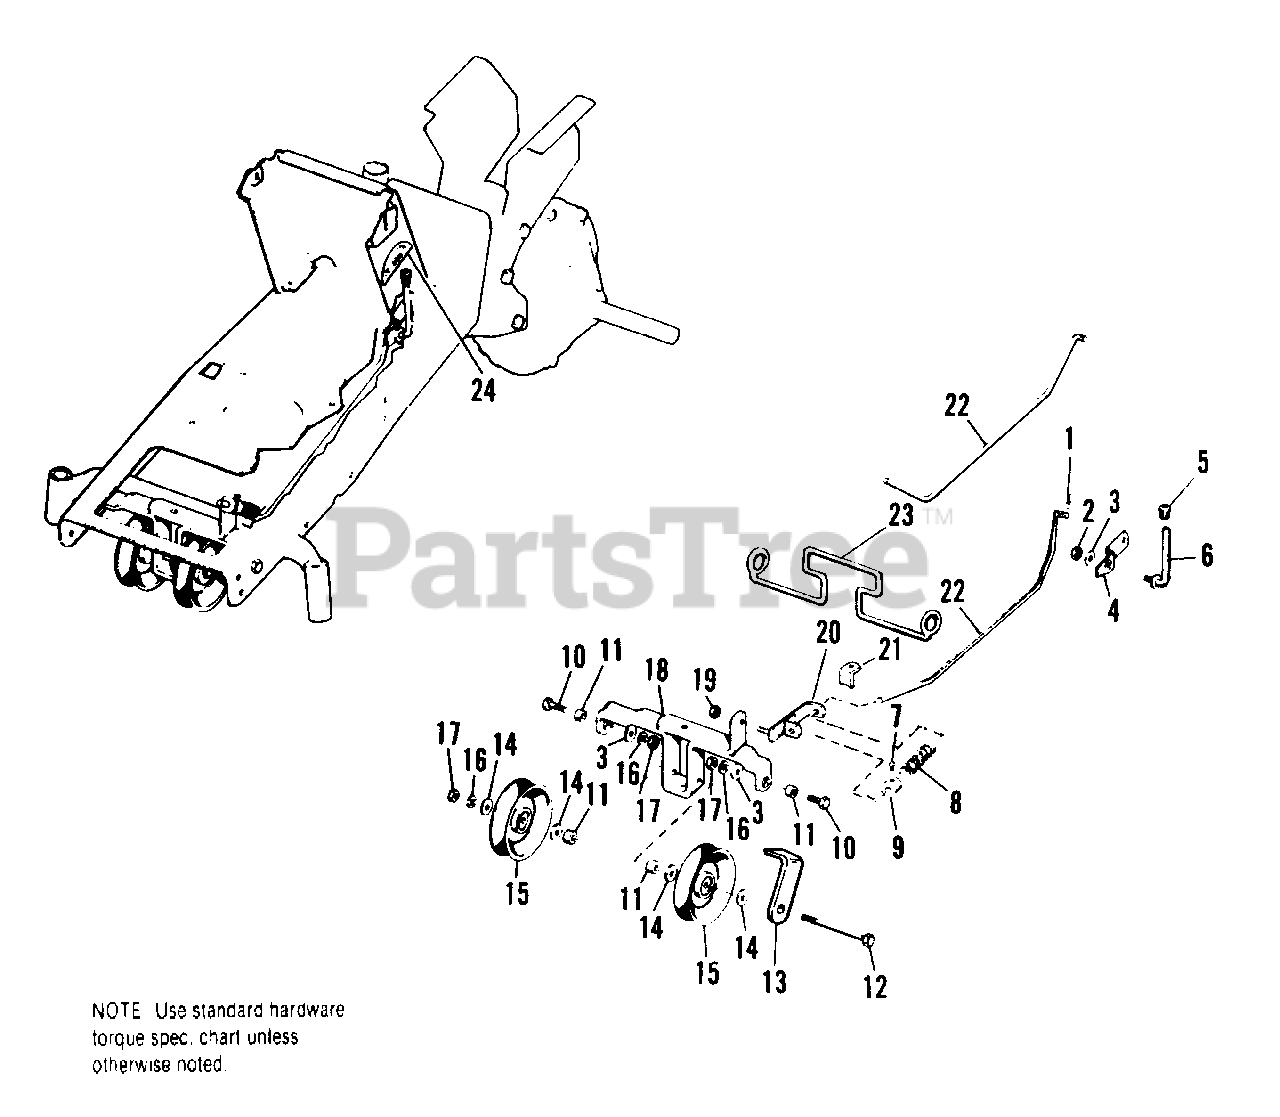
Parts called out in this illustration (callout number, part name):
1	PIN, Cotter, 3/32 x 3/4
2	LOCKNUT, Hex, 3/8-16
3	WASHER, Plain, 3/8
4	LEVER, Handle
7	SETSCREW, 1/4-20 x 3/8
8	SPRING (990481 Only)
9	COLLAR, Set
10	CAPSCREW, Hex Hd., 3/8-16 x 1
11	SPACER (990481 Only)
12	CAPSCREW, Hex Hd., 3/8-16 x 4-1/4
13	STOP, Belt (Not used on 990481 Only)
14	WASHER, Plain, 5/16
15	PULLEY, Idler
16	LOCKWASHER, 3/8
17	NUT, Hex, Full, 3/8-16
18	CLEVIS ASSY., Pulley
19	LOCKNUT, Hex, 5/16-18
20	GUIDE ASSY., Rod
21	BRACKET (990597, 990597, 990776, 990777 Only)
22	ROD, Clutch
22	ROD, Clutch (990481 Only)
23	STOP, Belt
24	DECAL, P.T.O.
